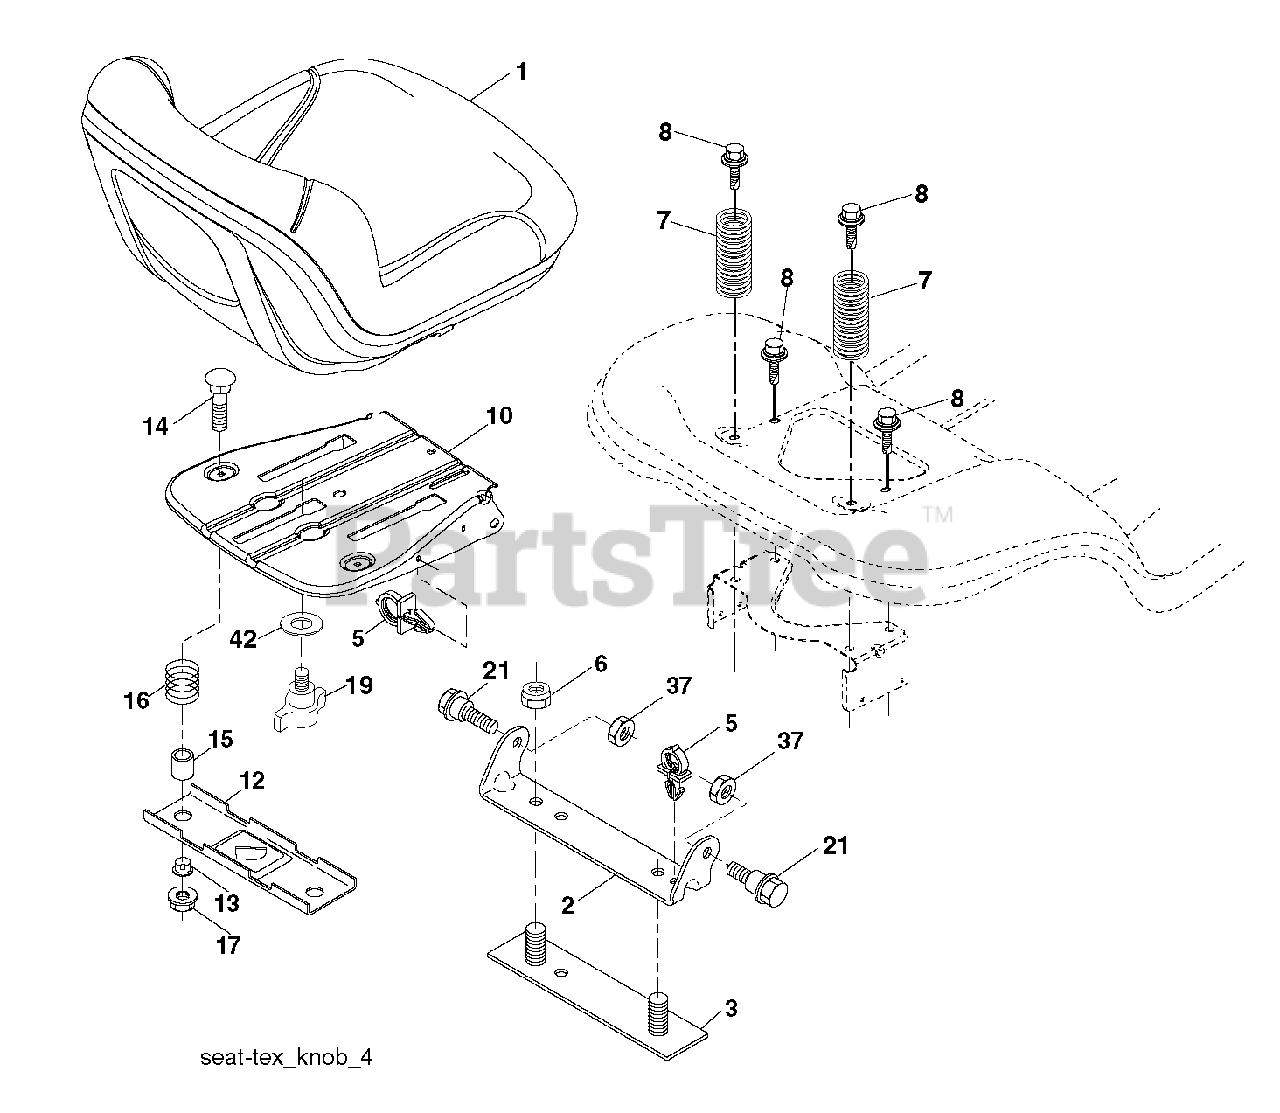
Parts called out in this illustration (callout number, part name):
1	SEAT.TP150.BLK.PPRO.KB/SL
2	BRKT.PIVOT.FENDER
5	PUSH CLIP
6	NUT
7	Compression Spring, Seat Black
8	BOLT, 5/16-18 X 1 3/4
10	PAN.ASM.SEAT.SHORT.SLD.ADJ.TEX
12	BRKT.MNT.OPC.SW.SEAT.
14	BOLT.ROUND.HEAD.SQUARE.NECK
15	SPACER SPLIT 28X.96
16	NUT T
17	NUT T
19	KNOB.SEAT.ADJ.
21	Shoulder Bolt, 5/16-18 X 5/8
37	NUT.71038.31-18.HEX.NYLOCK
42	WASHER.CUP.SEAT.
